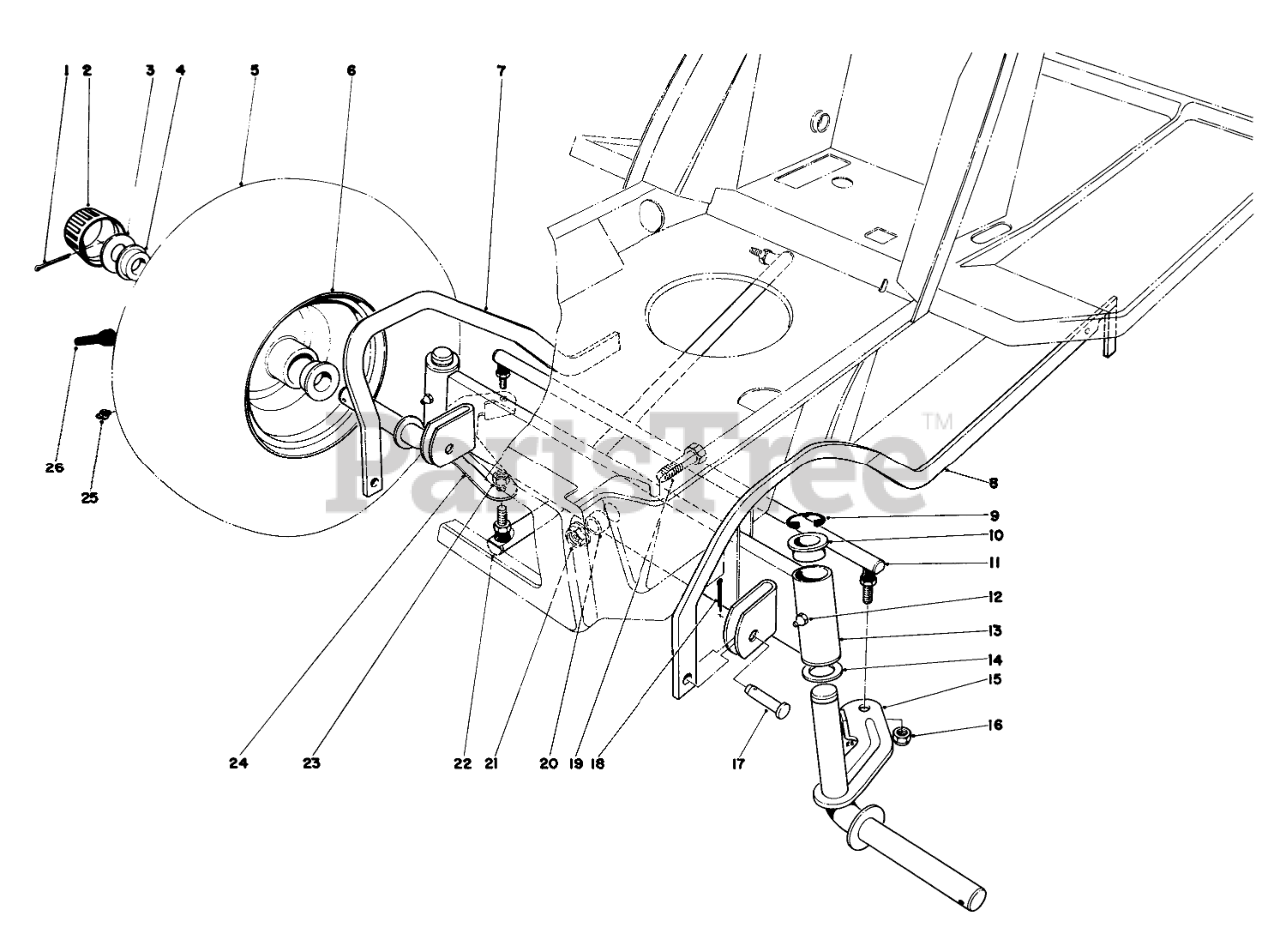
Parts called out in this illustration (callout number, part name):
1	PIN-COTTER
2	Cap-Hub
3	WASHER-PLAIN
4	Bearing
5	FRONT TIRE
6	FRONT RIM
7	R/F SCISSORS LINK WAB
8	LF SCISSORS LINK WAB
9	E-RING
10	BEARING-FLANGE
11	Tie Rod Steering
12	GREASE FITTING
13	Front Axle (Incl. Ref. #10)
14	WASHER-THRUST
15	LH SPINDLE WA PP
16	NUT-LOCK NI
17	PIN-CLEVIS
18	PIN-COTTER
19	SCREW-HH
20	SPACER-AXLE, FRONT
21	NUT-HF
22	STEERING ARM B
23	Nut
24	RH SPINDLE WA PP
25	FITTING-GREASE
26	STEM-VALVE
